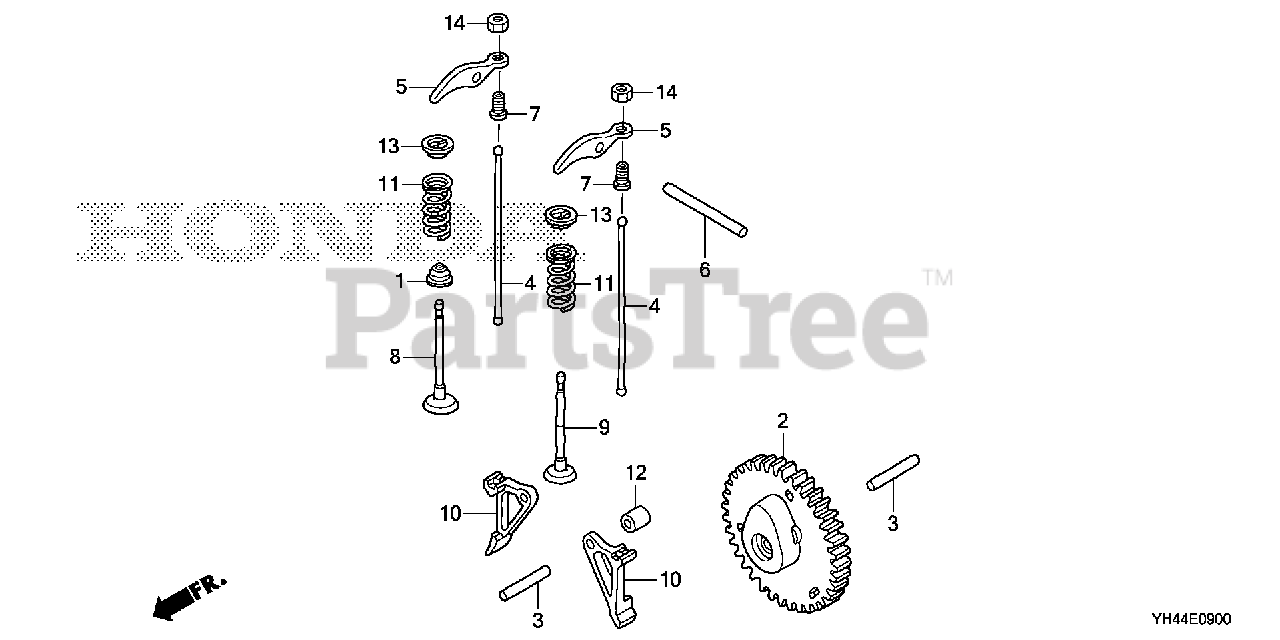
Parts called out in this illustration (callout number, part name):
1	SEAL, VALVE STEM
2	CAMSHAFT ASSY.
3	ROLLER (5X29.8)
5	ARM, VALVE ROCKER
6	ROLLER (4X37.8)
7	PIVOT, ROCKER ARM
8	VALVE, IN.
9	VALVE, EX.
10	LIFTER, VALVE
11	SPRING, VALVE
12	COLLAR, LIFTER
13	RETAINER, VALVE SPRING
14	NUT, TAPPET ADJUSTING
